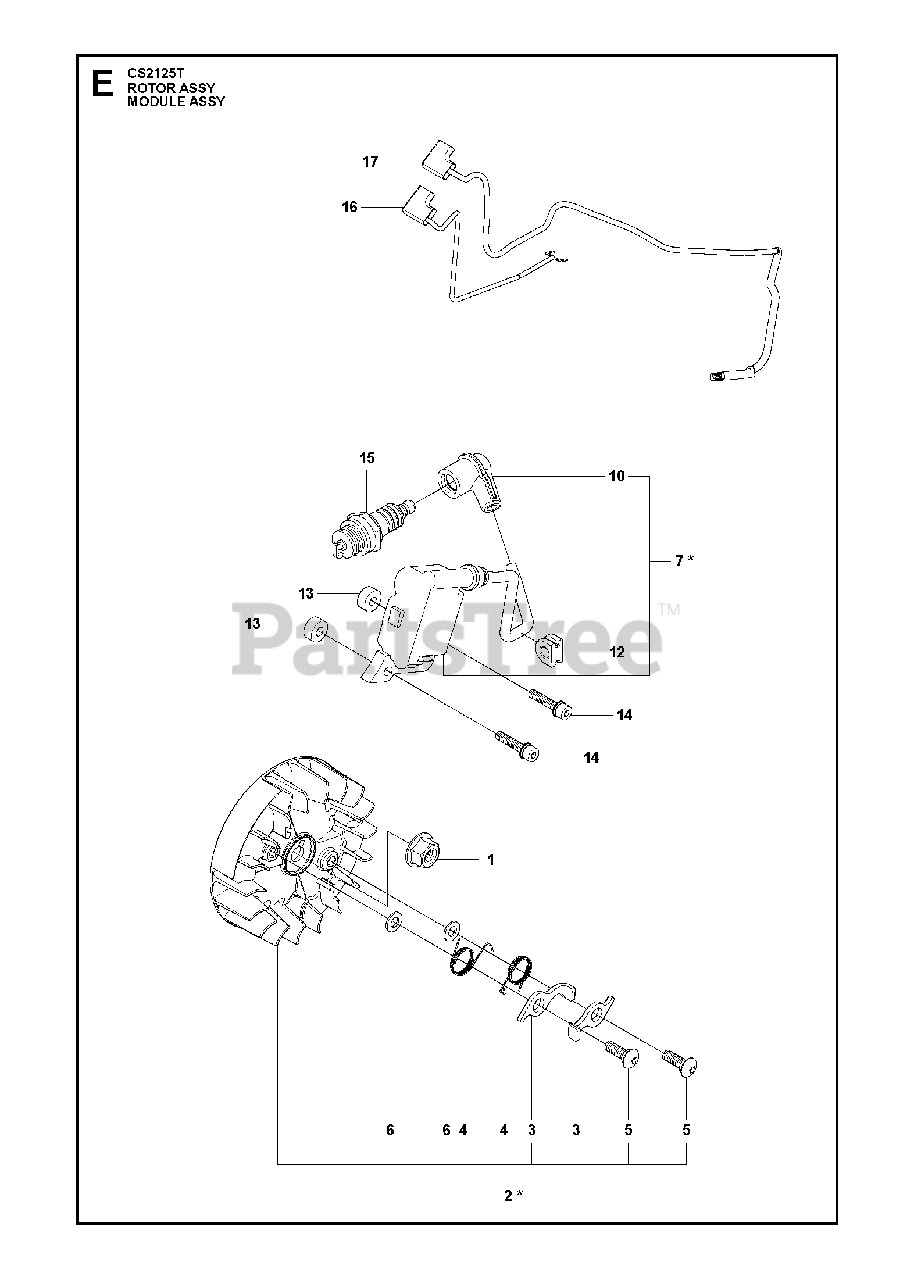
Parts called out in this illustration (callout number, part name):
1	NUT
6	WASHER 5X10X10
15	SPARK PLUG RCJ7Y
